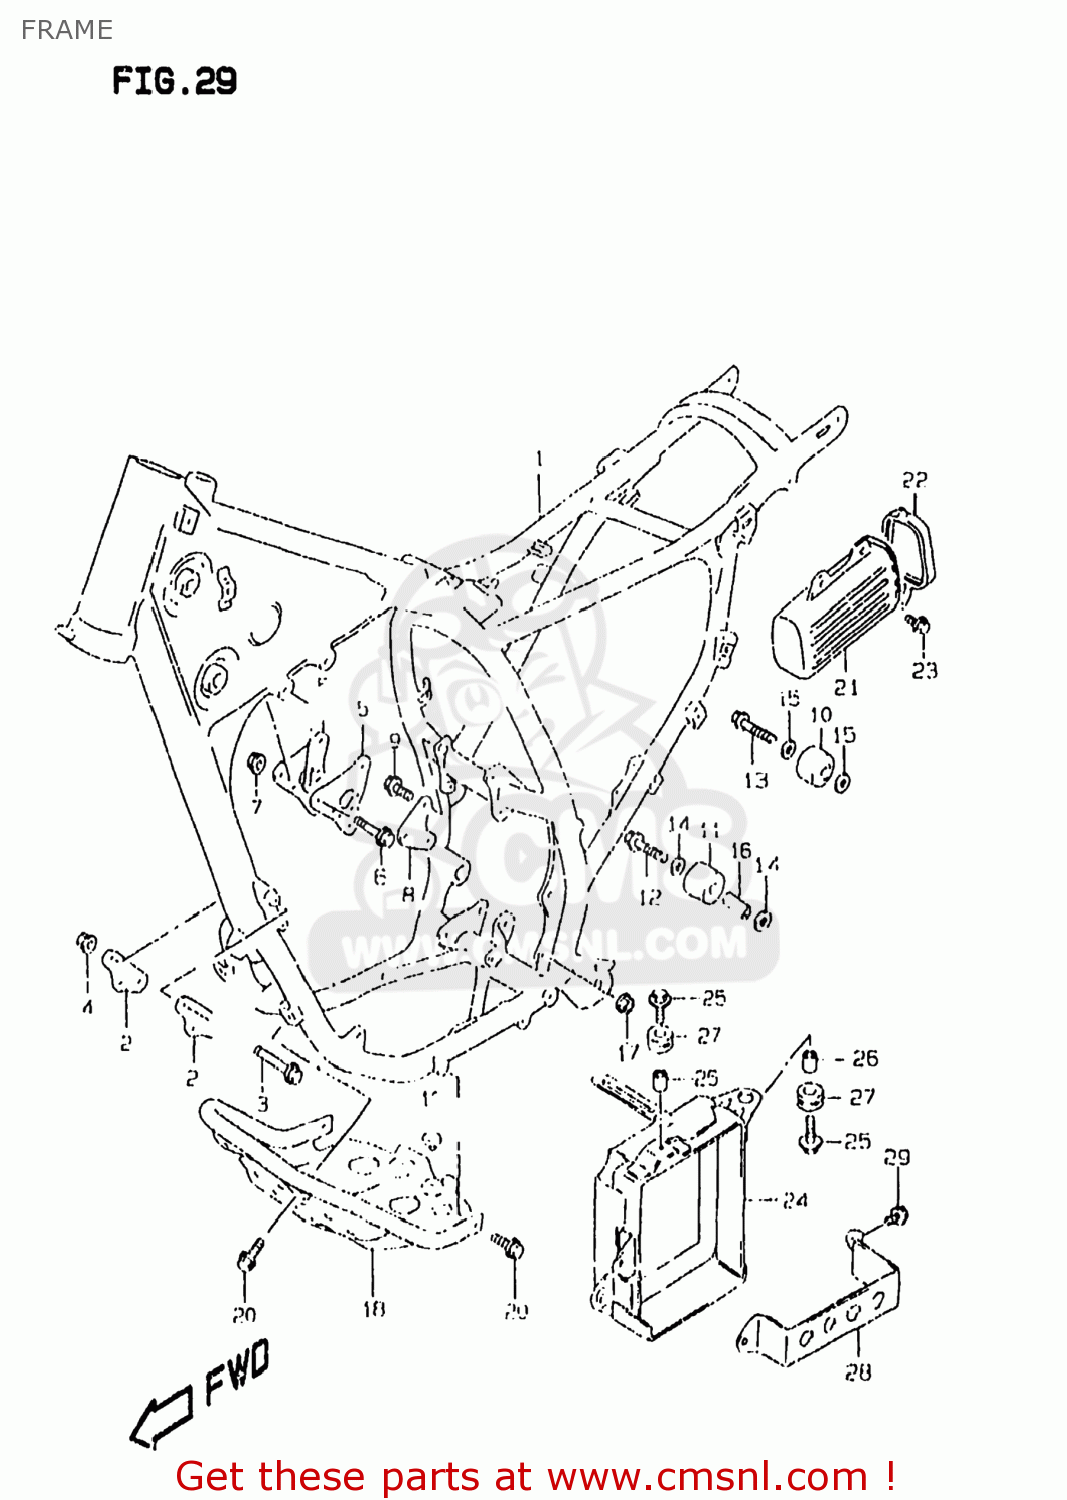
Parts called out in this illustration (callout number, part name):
1	FRAME (PURPLE)
2	PLATE,ENGINE MOUNT FR
3	BOLT(8X85)
4	NUT
5	PLATE,ENGINE MOUNT UPR
6	BOLT(8X70)
7	NUT
8	PLATE,ENGINE MOUNTING,REAR
9	BOLT(8X16)
10	ROLLER,CHAIN
11	ROLLER,CHAIN CONTROL
12	BOLT(8X38)
13	BOLT 8X45
14	WASHER
15	SHIM(8X12X1)
16	SPACER(8.6X12X25.5)
17	NUT
18	PROTECTOR,ENGINE(SILVER)
19	CUSHION
20	BOLT
21	HOLDER,TOOL
22	CAP,TOOL HOLDER
23	BOLT 6X16
24	HOLDER,BATTERY
25	BOLT(6X20)
26	SPACER(6.5X10X9)
27	CUSHION
28	COVER,BATTERY HOLDER
29	SCREW(6X10)
